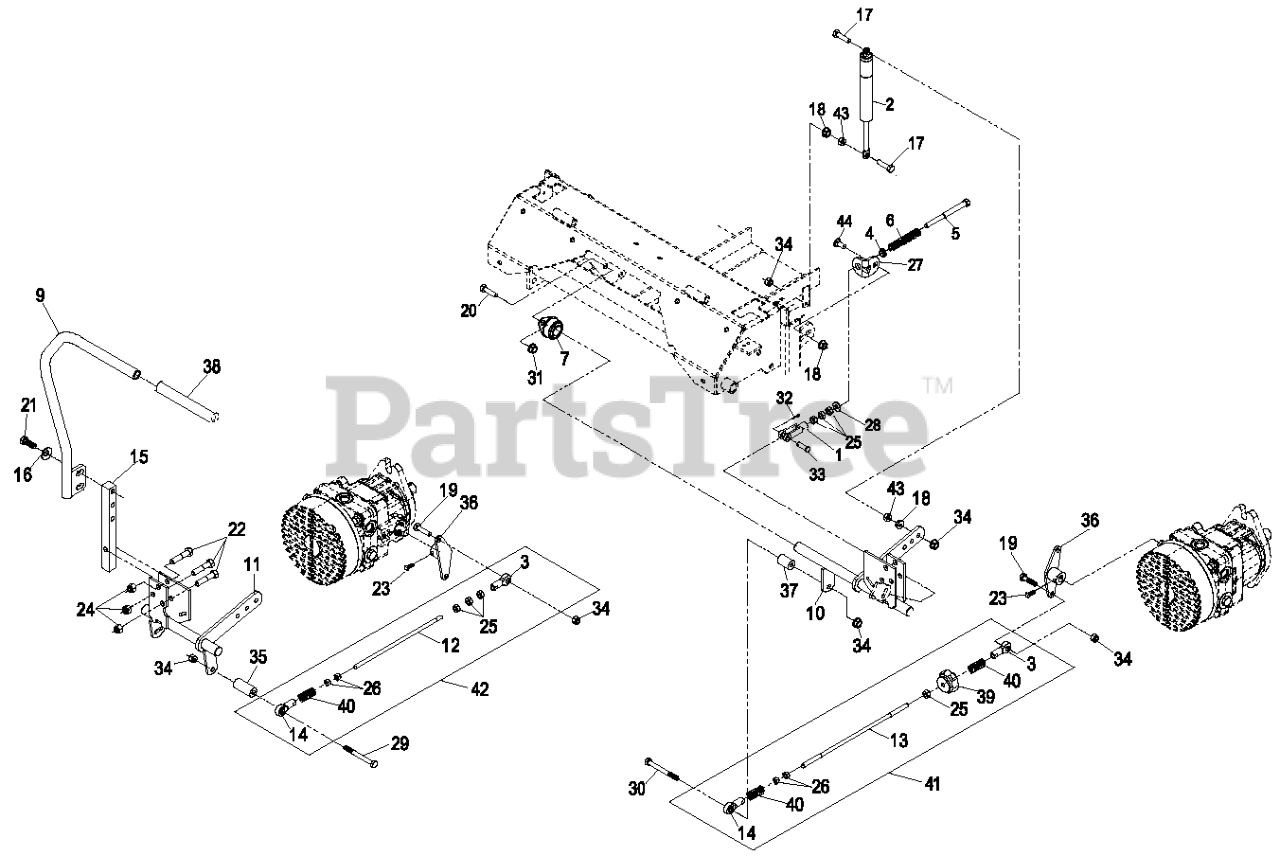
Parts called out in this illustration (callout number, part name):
1	YOKE-ADJUSTABLE
2	DAMPER-CONTROL, MOTION
3	BALLJOINT-RH
4	BUSHING-NYLON, FLANGED
5	BOLT-RETURN, NEUTRAL
6	SPRING-RETURN, NEUTRAL
7	BEARING-FLANGE, SIDE
9	ASM.RH LEVER/GRIP
11	CONTROL-MOTION, RH
12	LINK,XP HYDRO CONNECT RH
13	LINK,TRACKING ROD XP
14	BALLJOINT-LH
15	ARM-SHAFT, CONTROL
16	WASHER-BELLEVILLE
17	SCREW-HH
19	SCREW-HH
20	SCREW-HH
21	SCREW-HH
22	SCREW-HH
23	SCREW-SET
24	NUT-LOCK, NI
25	NUT-HEX
27	TAB-ADJUSTMENT
28	WASHER-FLAT
29	SCREW-HH
30	SCREW-HH
31	NUT-HHF, WHIZ
32	PIN-COTTER
33	PIN-CLEVIS
34	NUT-LOCK, NI
35	SPACER-CONTROL, HYD
36	ARM-CONTROL, HYDRO
37	SPACER-HYDRO CONTROL, LH
38	GRIP,CONTROL LEVER
39	KNOB-TRACKING
40	SPRING-COMPRESSION
41	TRACKING ROD ASM
42	RH HYD CONNECT LINK ASM
43	NUT-HEX
44	SCREW-CARR
